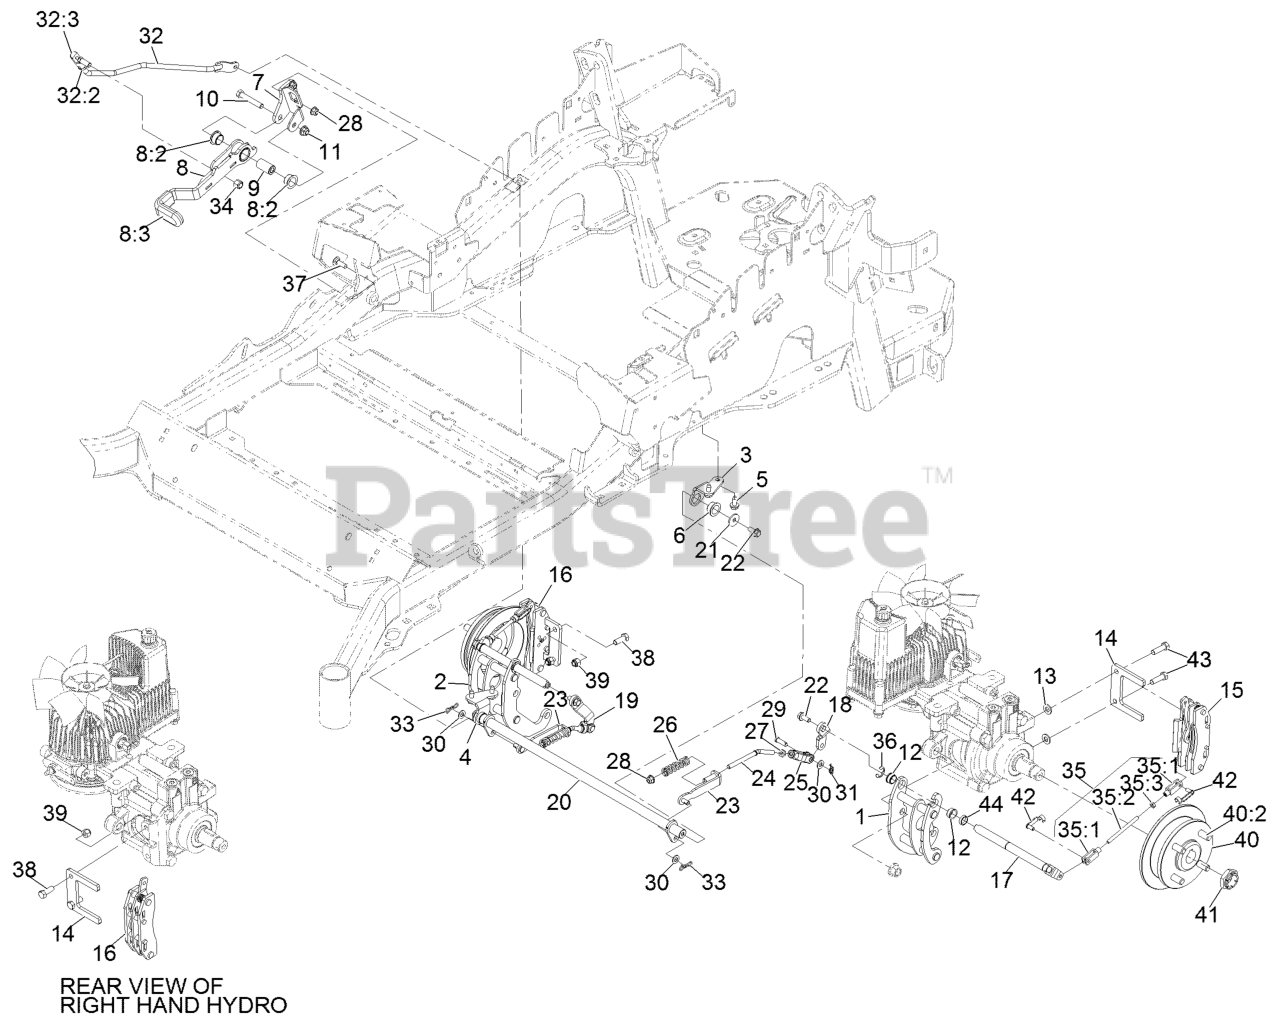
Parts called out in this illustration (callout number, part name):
1	MOUNT-BELLCRANK, LH
2	MOUNT-BELLCRANK, RH
3	MOUNT-PIVOT, LH
4	MOUNT-PIVOT, RH
5	Screw-HWH 5/16-18 X 3/4 Tf
6	BUSHING-FLANGE
7	BRACKET-MOUNT
8	BRAKE LEVER ASM
8:2	BUSHING-FLANGE
8:3	GRIP-LEVER
9	HANDLE-PIVOT, BRAKE
10	SCREW-HH
11	NUT-HF, NI
12	BUSHING
13	WASHER-FLAT
14	PLATE-MOUNT, BRAKE
15	CALIPER-BRAKE
16	CALIPER-BRAKE, RH
17	BELLCRANK
18	ARM-INNER, LH
19	ARM-INNER, RH
20	SHAFT-CROSS
21	WASHER-FLAT
22	SCREW-HHF
23	BRACKET-L
24	LINKAGE-MID
25	YOKE-OFFSET
26	SPRING-COMPRESSION
27	NUT-JAM
28	NUT-HF, NI
29	PIN-CLEVIS
30	WASHER-PLAIN
31	PIN-COTTER, LOCKING
32	FRONT LINKAGE ASM
32:2	END-TIE ROD, RH
32:3	NUT-HJ
33	PIN-COTTER, LOCKING
34	NUT-LOCK
35	REAR LINKAGE ASM
35:3	NUT-JAM
37	BOLT-CARR
38	SCREW-HH
39	NUT-LOCK, NI
40	WHEEL HUB ASM
40:2	STUD-WHEEL
41	LOCKNUT
42	PIN-CLEVIS, SPRING
43	SCREW-LOCK, PATCH
